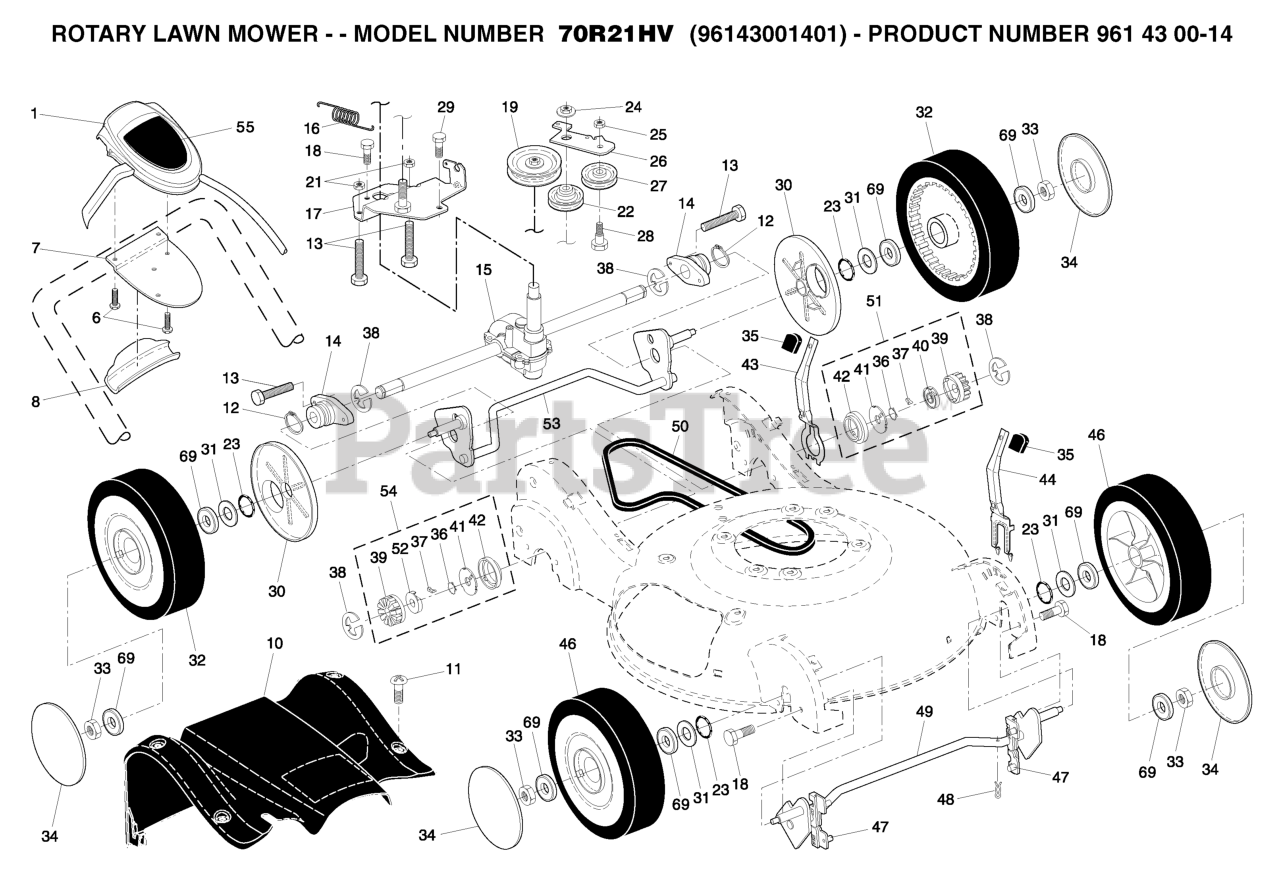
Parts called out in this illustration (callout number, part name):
1	CONTROL.DR.HV.RWGD.GRY/BLU
6	SCREW, PHILLIPS HEAD 10 X 5/8
7	BRACKET.DRIVE.CONTROL.MOUNT.BL
8	EZ WALK SNAP COVER PLATE
10	COVER ASM. DRIVE
12	RETAINING RING (2 2)(3 2)
13	SCREW.1/4-20X21/4.HEX.
14	BEARING.SUPPORT.ASSEM
15	TRANSMISSION.21.HI-VAC.EZ
16	SPRING.RETURN
17	BRKT.TRANSMISSION.HV.E
21	NUT
22	PULLEY.IDLER.V-BELT
23	O-RING
24	NUT
25	NUT.CENTERLOCK.5/16-
26	ARM.IDLER.BZP
27	IDLER PULLEY
28	SHOULDER BOLT
29	SCREW 14-20 X 5/8
30	DUST COVER, WHEEL
31	WASHER.FLAT.1/2
32	WHEEL.9X2.25.PR.JUNG.BLK
33	HEX FLANGE LOCKNT
34	RB HUBCAP.3-SPOKE.SILVER
35	KNOB.SELECTOR.SPRG.H-GRY (2 2)
36	SPRING, TORSION
37	PAWL.DRIVE.21.EZ-WALK
38	E-RING 7/16 RE
39	GEAR, PINION
40	RETAINER.DRIVE.21.EZ-WALK.LT
41	DISC.DRIVE.21.EZ-WALK
42	SEAL.PINION
43	LEVER, SELECTOR, HEIGHT, REAR
44	LEVER, SELECTOR, HEIGHT, FRONT
46	WHEEL.9X2.25.LP.JUNG.BLACK
47	BUSHING.FRONT.TORQUE.SHAFT
48	SPRING RETAINER
49	SHAFT FRONT
50	BELT.DRIVE.EZ.WALK.HI-VAC
51	PINION ASSY, LH
52	RETAINER, DRIVE, RH
53	AXLE.ASM.REAR.TORQUE.BZP
54	PINION ASSY, RH
69	BEARING.8".WHEEL
